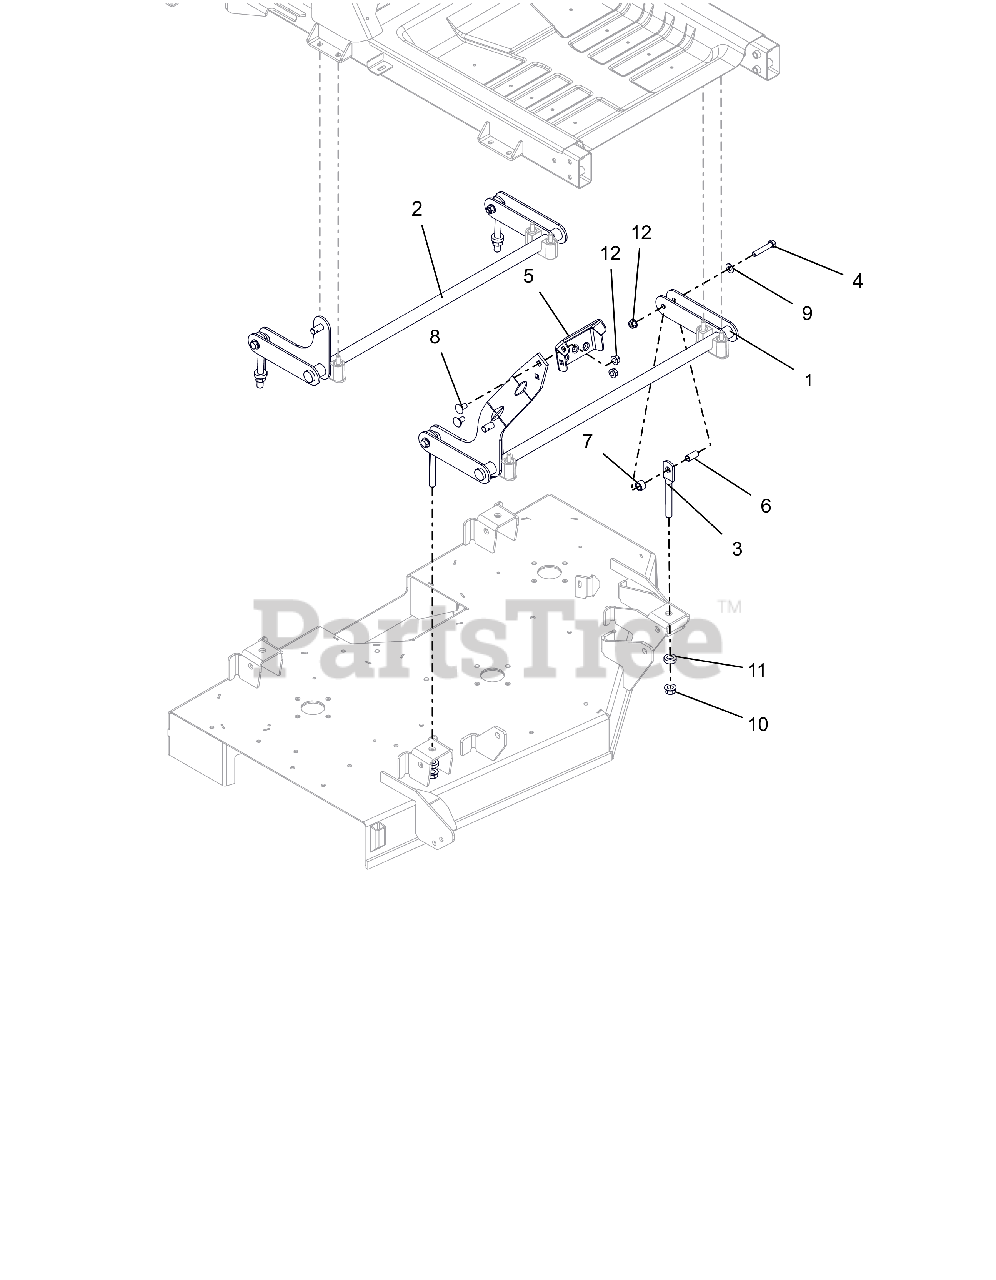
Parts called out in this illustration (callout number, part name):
1	WLDMT, FRONT DECK LIFT PIVOT
2	WLDMT, REAR DECK PIVOT
3	LINK,DECK (HOLE-LONG)
4	BLT, HEX .38-16X2.00 G8 ZCC
5	PEDAL, DECK LIFT (BOLT ON)
6	BSHG-SLV .385X.500X1.045
7	BSHG-SLV .510X.751X.475
8	BLT,RHSN .38-16X.75 G5 BFP
9	WSHR,FLT .406X.812X.065 ZCC
10	NUT-LK-CTR-FLG .500-13 GG ZCC
11	WASHER, RUBBER
12	NUT-LK-CTR-FLG .375-16 GF ZCC
